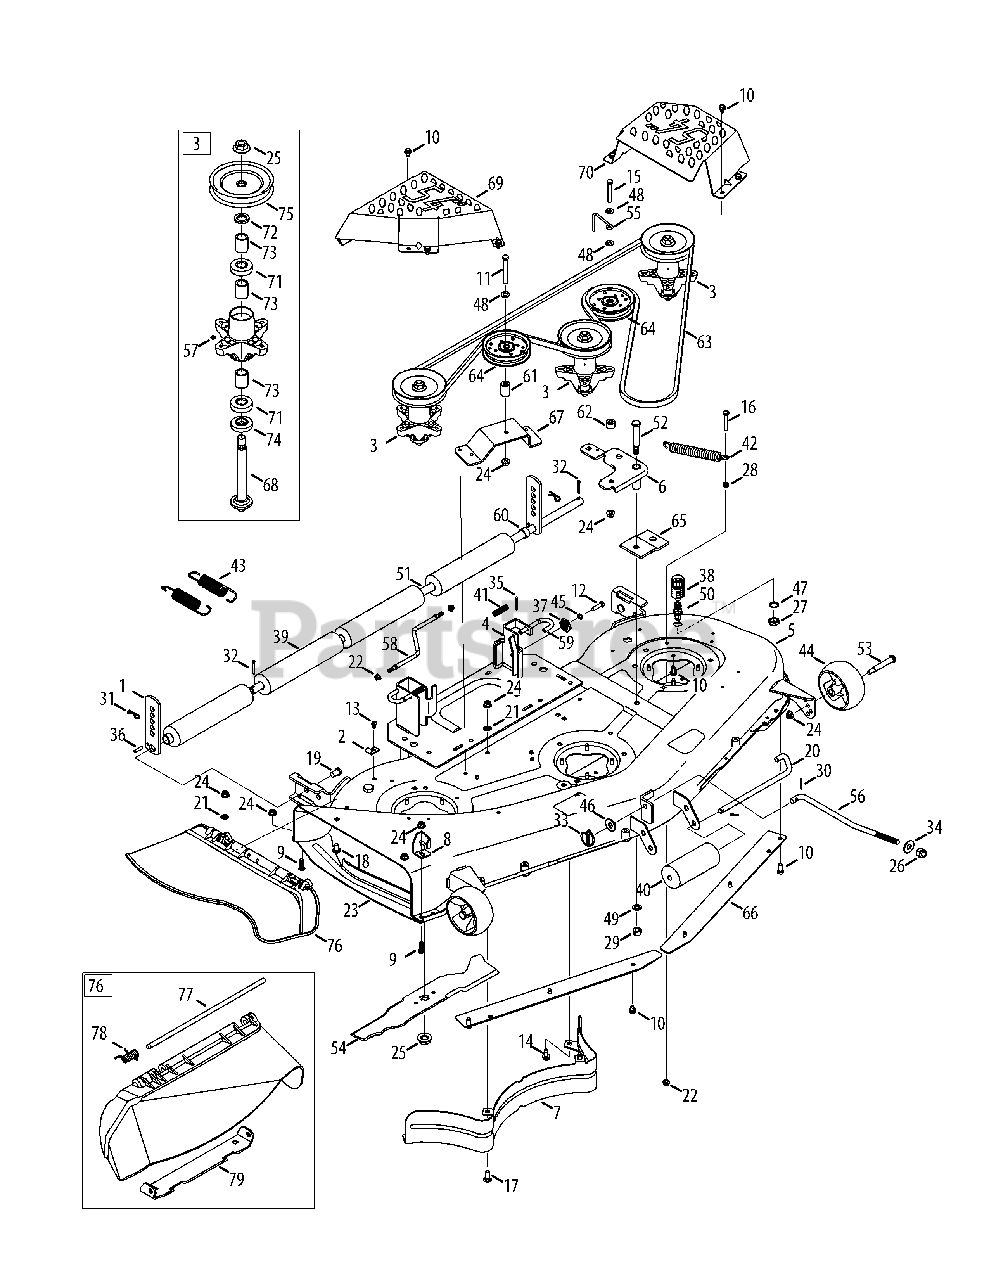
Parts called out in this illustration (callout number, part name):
1	Height Adjust Bracket
2	Retainer Hook Bracket
3	Spindle Assembly
4	Deck Hanger Bracket Assembly
5	Deck Assembly
6	Idler Assembly
9	Hex Screw, 3/8-16x1.00
10	Taptite Screw, 5/16-18x.750
11	Hex Screw, 3/8-16x3.00
12	Hex Screw, 5/16-18x1.25
13	Hex Screw, 1/4-20 x .500
14	Taptite Screw, 3/8-16x0.750
15	Hex Screw, 3/8-16x2.50
16	Hex Screw, 5/16-18x2.00
17	Carriage Bolt, 3/8-16x1.00
18	Carriage Bolt, 3/8-16x0.75
19	Clevis Pin, .50 DIA x .78 LG
20	Roller Pin, 1/2 DIA x 7.31 LG
21	Push Nut, 3/8
22	Flangelock Nut, 5/16-18
23	Finger Guard
24	Flangelock Nut, 3/8-16
25	Flange Nut, 5/8-18
26	Flexlock Nut, 1/2-13
27	Hex Nut, M16-1.5 DIN 936
28	Hex Nut, 5/16-18
29	Hexlock Nut, Counterlock, 1/2-13
30	Cotter Pin, 3/32x1.0
31	Click Pin, .092 x 1.64 LG
32	Cotter Pin, 5/32x1.25
33	Lynch Pin, .1875
34	Washer, .630 x 1.25 x .180
35	Cotter Pin, 1/8 x 1.25
36	Spring Pin, 1/4 DIA x 1.00 LG
38	Water Nozzle Adaptor
39	Deck Roller
40	Front Roller
41	Compression Spring, .535 OD x 1.751 LG
42	Extension Spring, .85 OD x 5.915 LG
43	Extension Spring, 1.15 OD x 5.99 LG
44	Deck Wheel
45	Lock Washer, 5/16
46	Flat Washer, .531 x 1.25 x .100
47	Lock Washer, 5/8
48	Flat Washer, .406 x .875 x .059
49	Lock Washer, 1/2
50	Deck Water Nozzle
51	Shaft, .750 x .47.12
52	Shield Screw, .625 x 2.50x1/2-13
53	Shoulder Bolt, .496 x 2.50x3/8-16
55	Belt Keeper Rod
56	Deck Lift Rod
57	Lube Fitting
58	Deck Sway Rod
59	Deck Release Pin
60	Spacer, .82 ID x 1.00 OD x .53
61	Spacer, .380 x .900 x 1.313
62	Spacer, .385 ID x .88 x .64
64	Idler Pulley, 4.25"DIA
65	Pulley Stabilizer Bracket
67	Stationary Idler Bracket
68	Spindle Shaft, 6.95 LG
69	RH Spindle Cover
70	LH Spindle Cover
71	Ball Bearing, .787 ID x 1.85 OD x .551
72	Spacer, .790 ID x 1.25 OD x .175
73	Spacer, .80 x 1.10 x 1.322 LG
74	Spacer, .79 x 1.82 x .55 LG
75	Deck Pulley
76	Chute Assembly
78	Torsion Spring, .44 ID x 2.0
79	Chute Bracket
